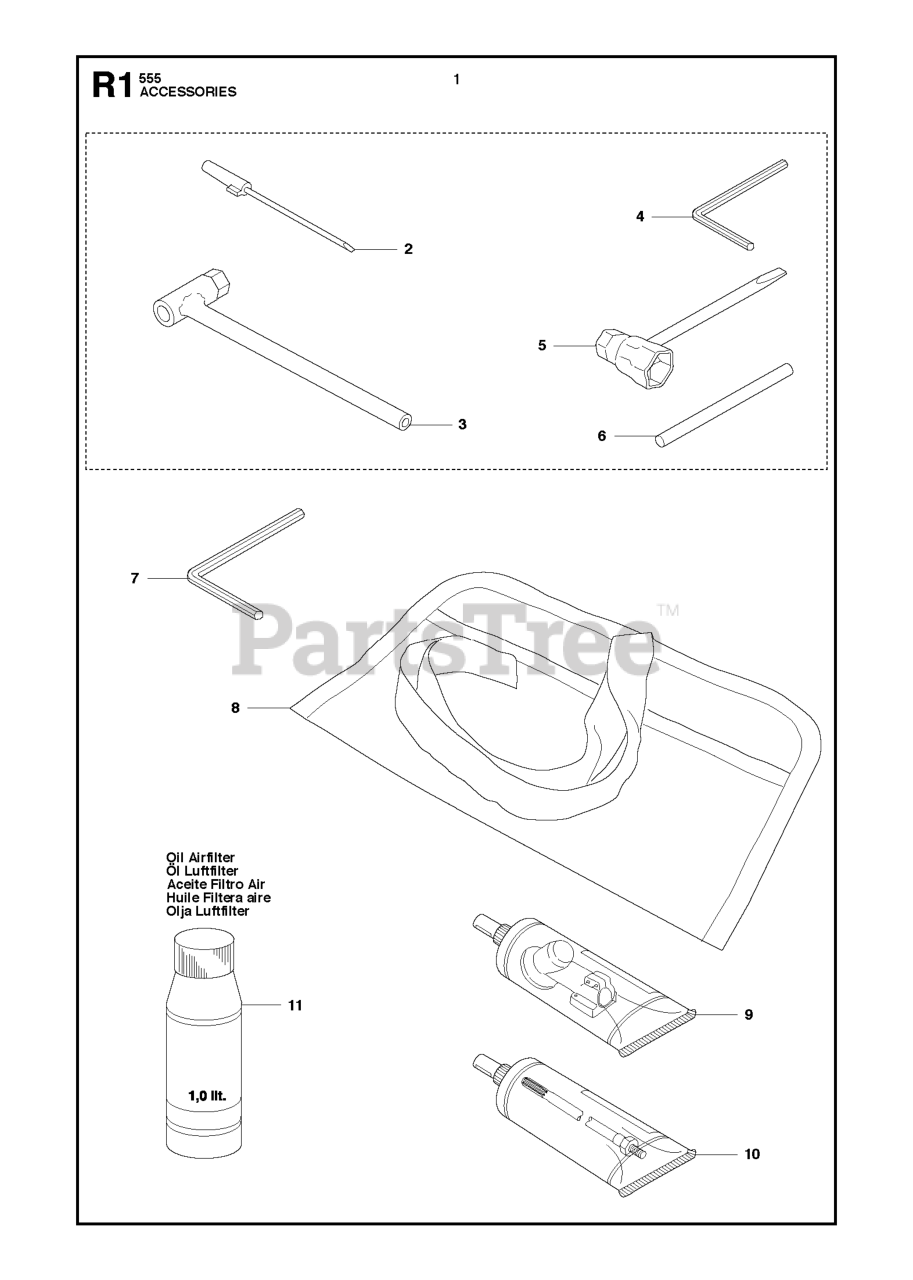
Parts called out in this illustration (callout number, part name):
1	RP ACCESSORY BAG
2	SCREWDRIVER
4	L-KEY WRENCH
5	COMBI TOOL
6	LOCKING PIN
7	KEY
9	BEVEL GEAR GREASE
10	DRIVE SHAFT GREASE (200 G)
11	Air Filter Oil 1l.
